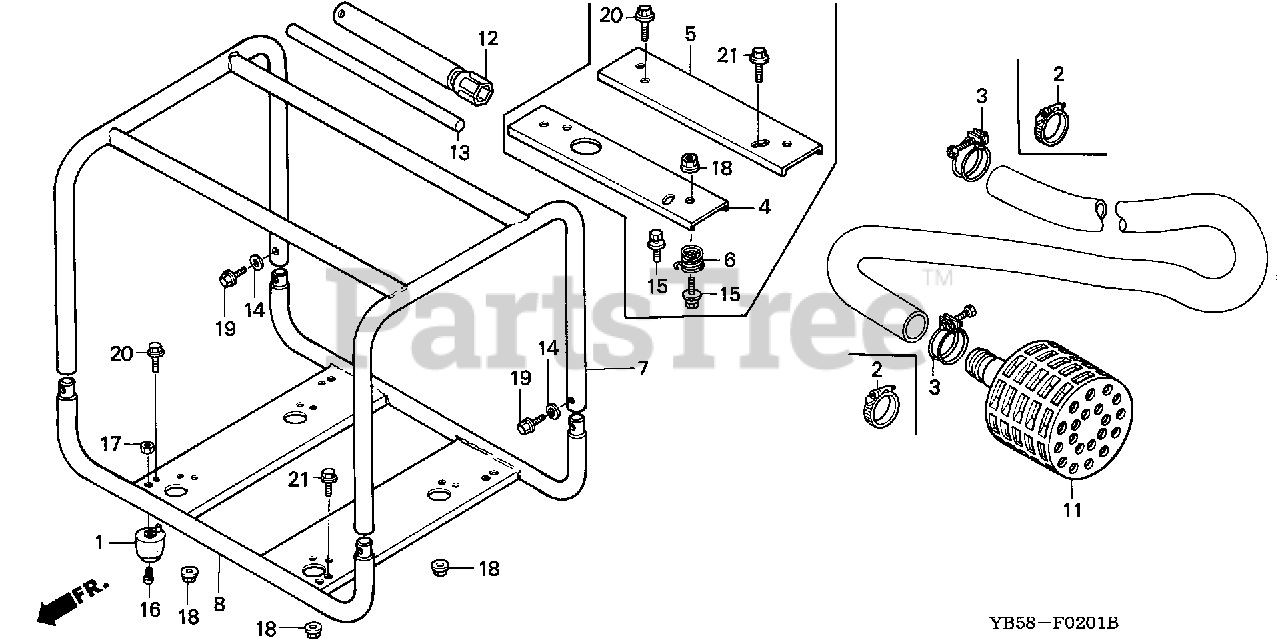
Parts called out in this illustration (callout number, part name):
1	RUBBER (LOWER)
3	BAND, HOSE
7	FRAME (UPPER)
8	FRAME (LOWER)
11	STRAINER (ENGINE NO.)
12	WRENCH, SPARK PLUG (ENGINE NO.)
13	HANDLE, BOX WRENCH (ENGINE NO.)
14	WASHER, FRAME JOINT
16	SCREW, PAN (6X10)
17	NUT, HEX. (6MM)
19	BOLT, FLANGE (8X18)
20	BOLT, FLANGE (8X25)
21	BOLT, FLANGE (8X28)
